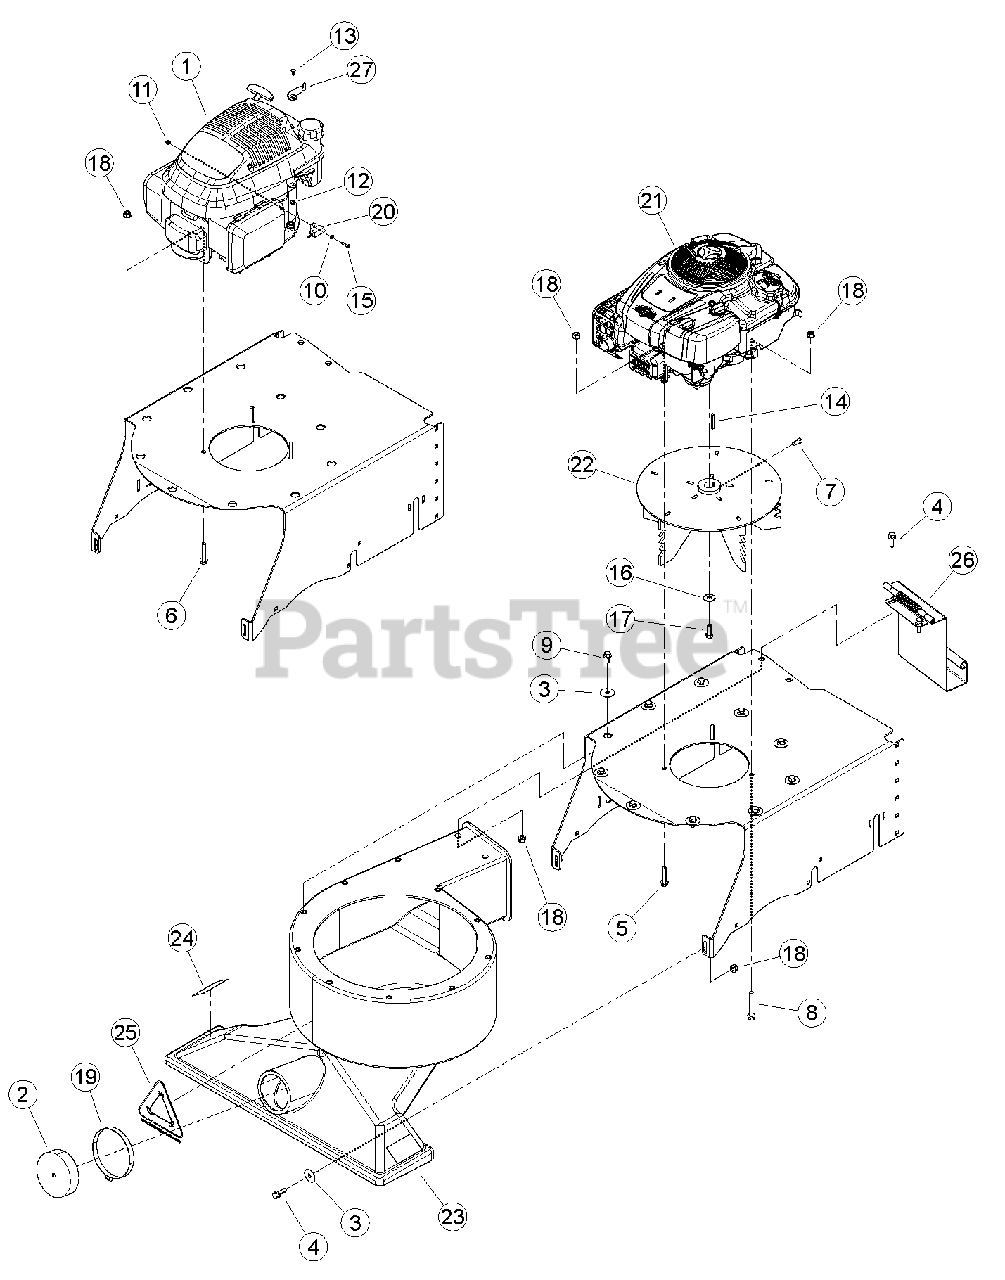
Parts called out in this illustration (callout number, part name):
1	ENGINE, 5.5 HP HONDA GCV (FOR SERVICE SEE ENGINE OWNER'S MANUAL OR NEAREST HONDA INDUSTRIAL ENGINE DEALER) (WV160 ONLY)
2	CAP, ROUND VINYL
3	WASHER, 5/16" FENDER ZP
4	BOLT, 5/16 X 1 FLANGE NC
5	BOLT, 5/16 X 1-1/2 FLANGE NC (WV190 ONLY)
6	BOLT, 5/16 X 1-3/4 FLANGE NC (WV160 ONLY)
7	SCREW, 5/16-18 X 5/8 SQ HD SET
8	BOLT, 5/16 X 2-1/2 FLANGE NC (WV190 ONLY)
9	BOLT, 5/16 X 5/8 FLANGE NC
10	WASHER, #8 SAE (WV160 ONLY)
11	NUT, 8-32 NYLOCK (WV160 ONLY)
12	NUT, 10/24 NYLOCK TYPE NM ZP (WV160 ONLY)
13	SCREW, MCH 10-24 X 1/2" PAN HD PH ZP (WV160 ONLY)
14	KEY, SQUARE 3/16" X 1-1/2" LG PLN
15	SCREW, MCH 8-32 X 3/4 PHP RDHD (WV160 ONLY)
16	WASHER, 3/8 GR8 USS ZP
17	BOLT, 3/8 X 1" NF GR8 ZP HHCS
18	NUT, 5/16-18 NYLOCK FLANGE
19	CLAMP, 4" HOSE
20	SWITCH, HONDA ENGINE KILL (WV160 ONLY)
21	ENGINE, BRIGGS VERT 190CC 850 SERIES (FOR SERVICE SEE ENGINE OWNER'S MANUAL OR NEAREST BRIGGS & STRATTON INDUSTRIAL ENGINE DEALER) (WV190 ONLY)
22	WELDMENT, BEARVAC ROTOR
23	ASSEMBLY, FAN INTAKE HOUSING W/ DECALS
24	DECAL, DANGER
25	LOGO, COLLECT IT (WHITE)
26	ASSEMBLY, EXHAUST DOOR
27	PLATE, HONDA BRAKE HOLDER (WV160 ONLY)
